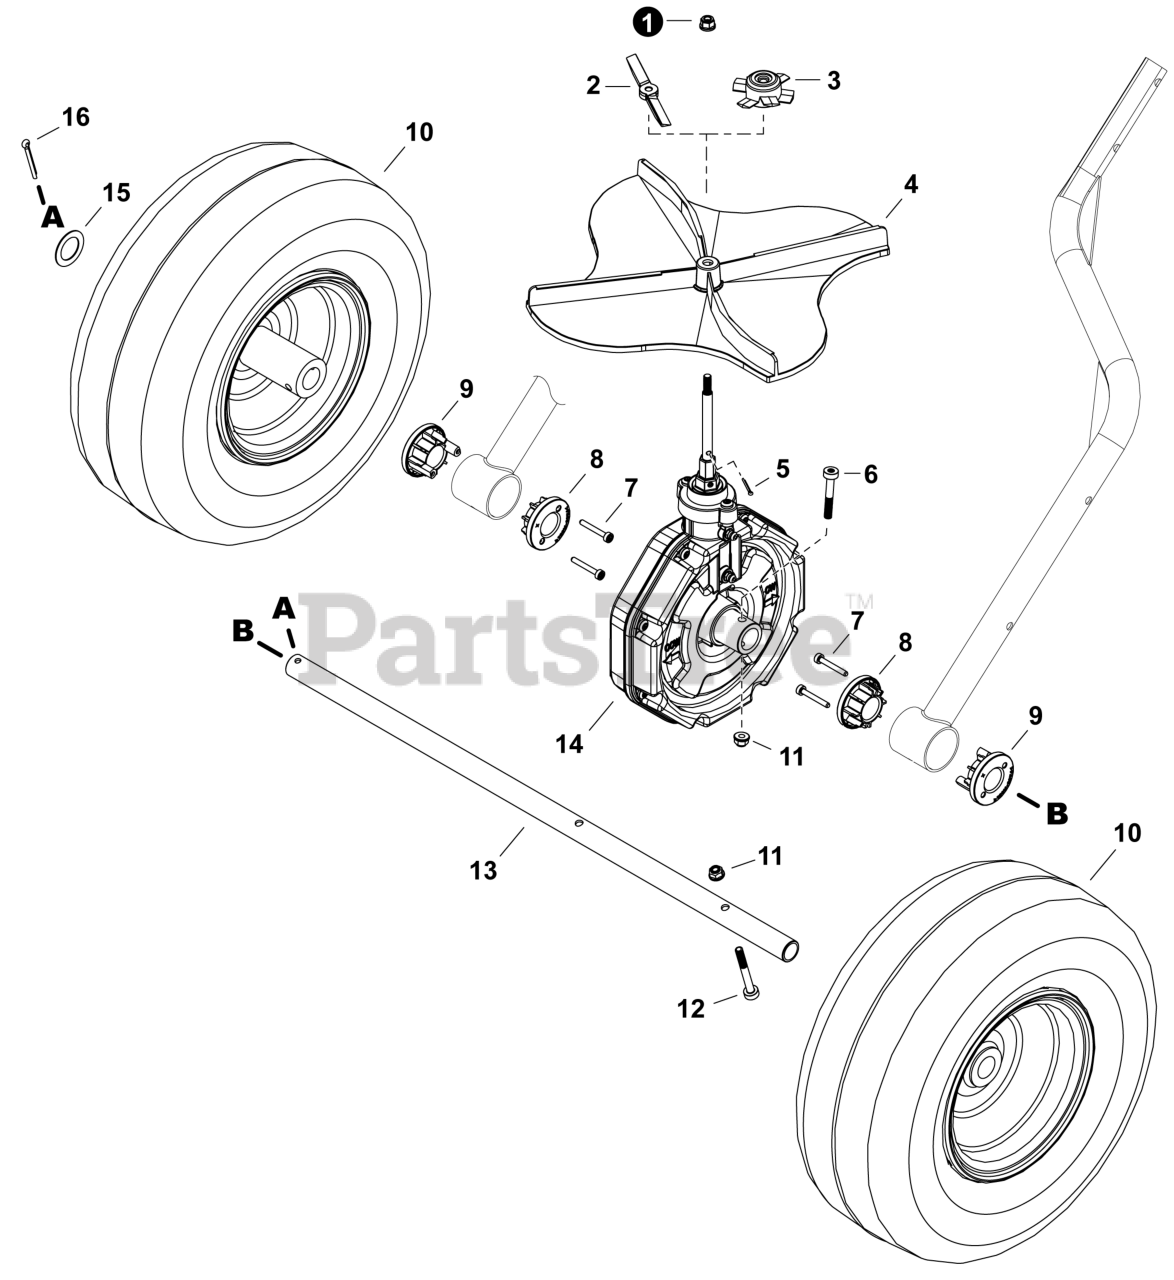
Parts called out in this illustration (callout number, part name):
2	AGITATOR
3	AGITATOR - SALT
4	PLATE, SPREADER
5	PIN - COTTER
6	BOLT 6x40
8	BUSHING, AXLE
9	BUSHING, AXLE (B)
11	NUT, FLANGE M6
12	BOLT, M6 X 50MM
14	GEAR CASE ASSY
16	PIN - COTTER
